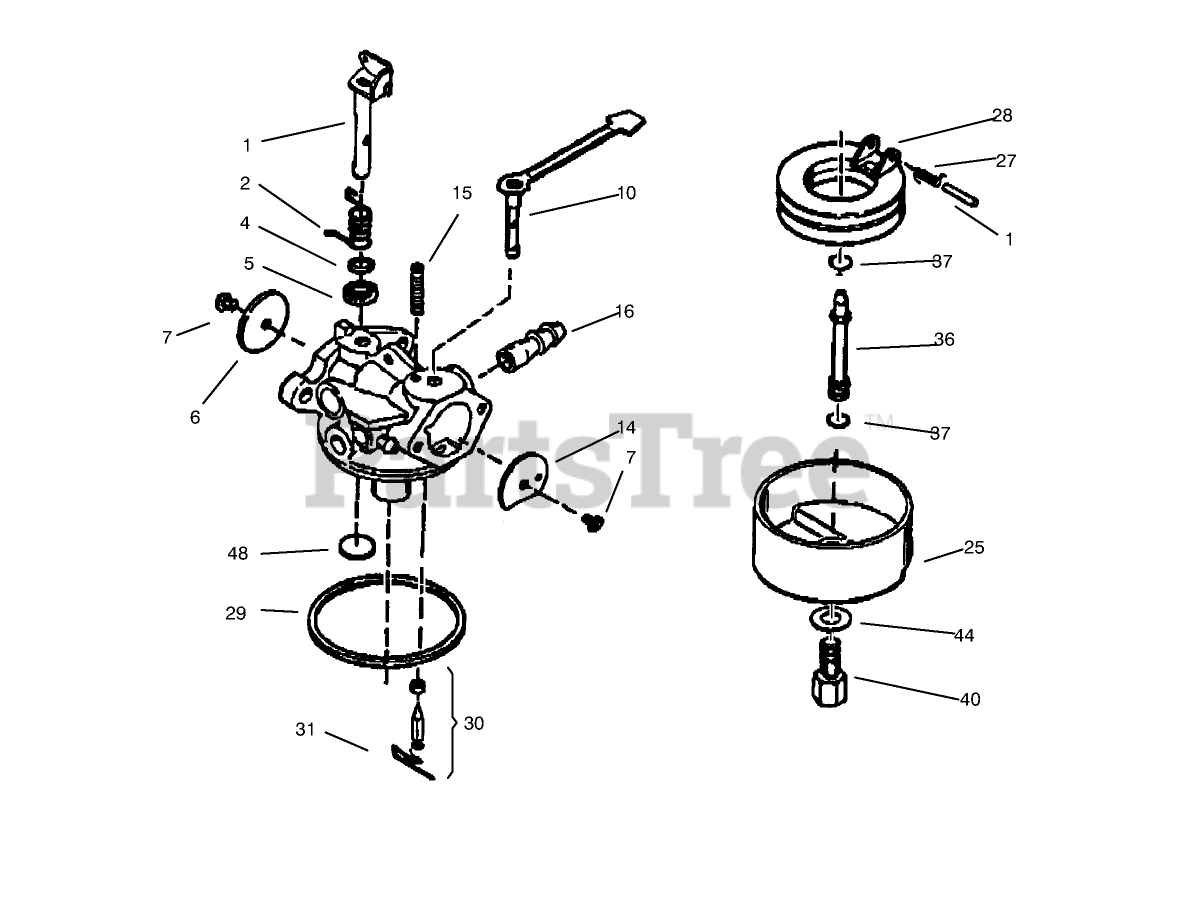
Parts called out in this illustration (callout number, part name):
1	Throttle Shaft and Lever ASM
2	Spring-Trottle, Return
4	Washer-Seal, Dust
5	Seal-Dust
6	Shutter-Throttle
7	Screw-Shutter
10	Choke Shaft and Lever ASM
14	Shutter-choke
15	Spring-Positioning, Choke
16	Fitting-Fuel
25	Bowl Float
26	Spring-Float, Dampening
27	Shaft-Float
28	Float
29	O Ring-Bowl, Float
30	Inlet Needle, Seat Clip Assy. (Incl. No. 13)
31	Clip-Spring
36	Tube-Nozzle, Main
37	O-Ring
40	Nut-Bowl, High Speed
44	Washer-Bowl Nut
48	Plug-Welch, Atmospheric Vent
